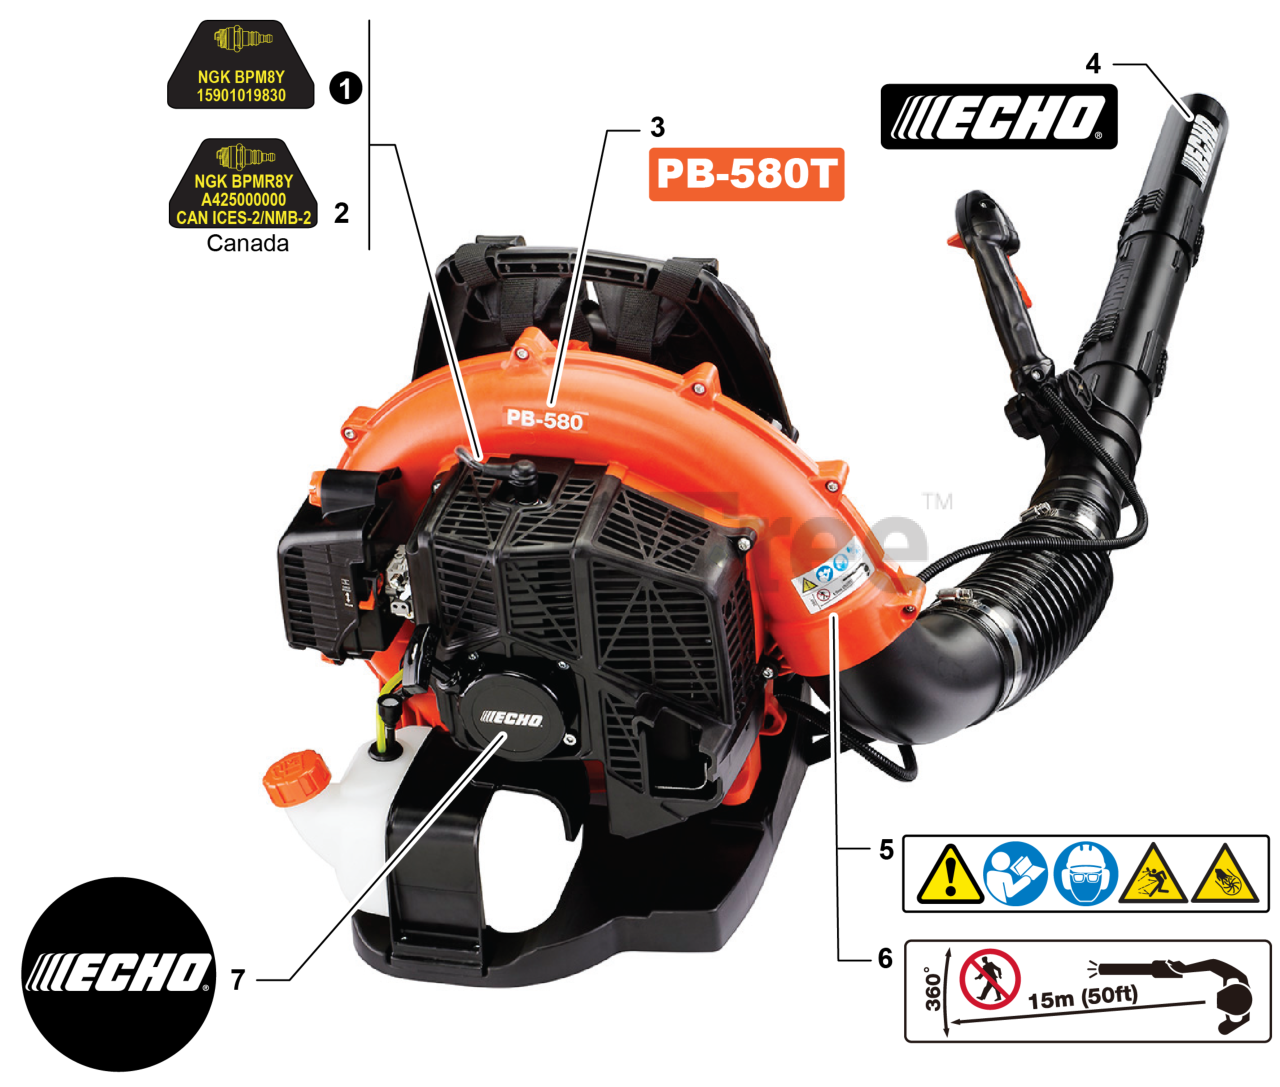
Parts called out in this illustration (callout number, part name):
1	LABEL - SPARK PLUG - BPM8Y
2	LABEL - SPARK PLUG - BPMR8Y
3	LABEL - MODEL - PB-580T
4	LABEL - ECHO
5	LABEL - CAUTION - ISO
6	LABEL - CAUTION - BLOWER
7	LABEL - STARTER - ECHO
